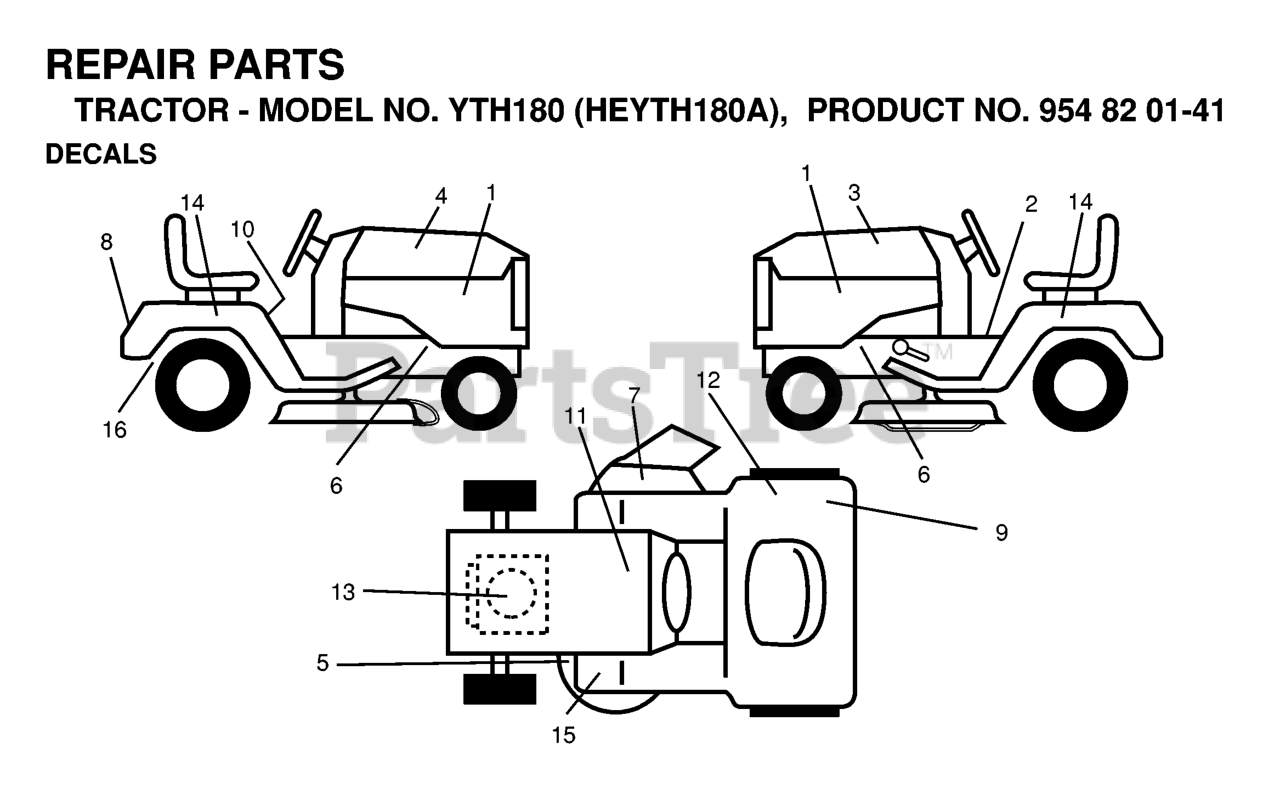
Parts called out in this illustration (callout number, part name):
1	DECAL PNL SIDE
2	DECAL PARK BRAKE
3	DECAL L.H. YTH180
4	DECAL R.H. YTH180
5	DECAL V BELT SCHEMATIC
6	DECAL
7	DECAL MOWER CUT/FINGER
8	DECAL FENDER HUSQ
9	DECAL CERTIFICATION
10	DECAL READ OWNER'S MAN SYMS
11	DECAL BTRY SYMBOLS
12	DECAL EUROPE STANDARD CE
14	DECAL
15	DECAL
16	DECAL
